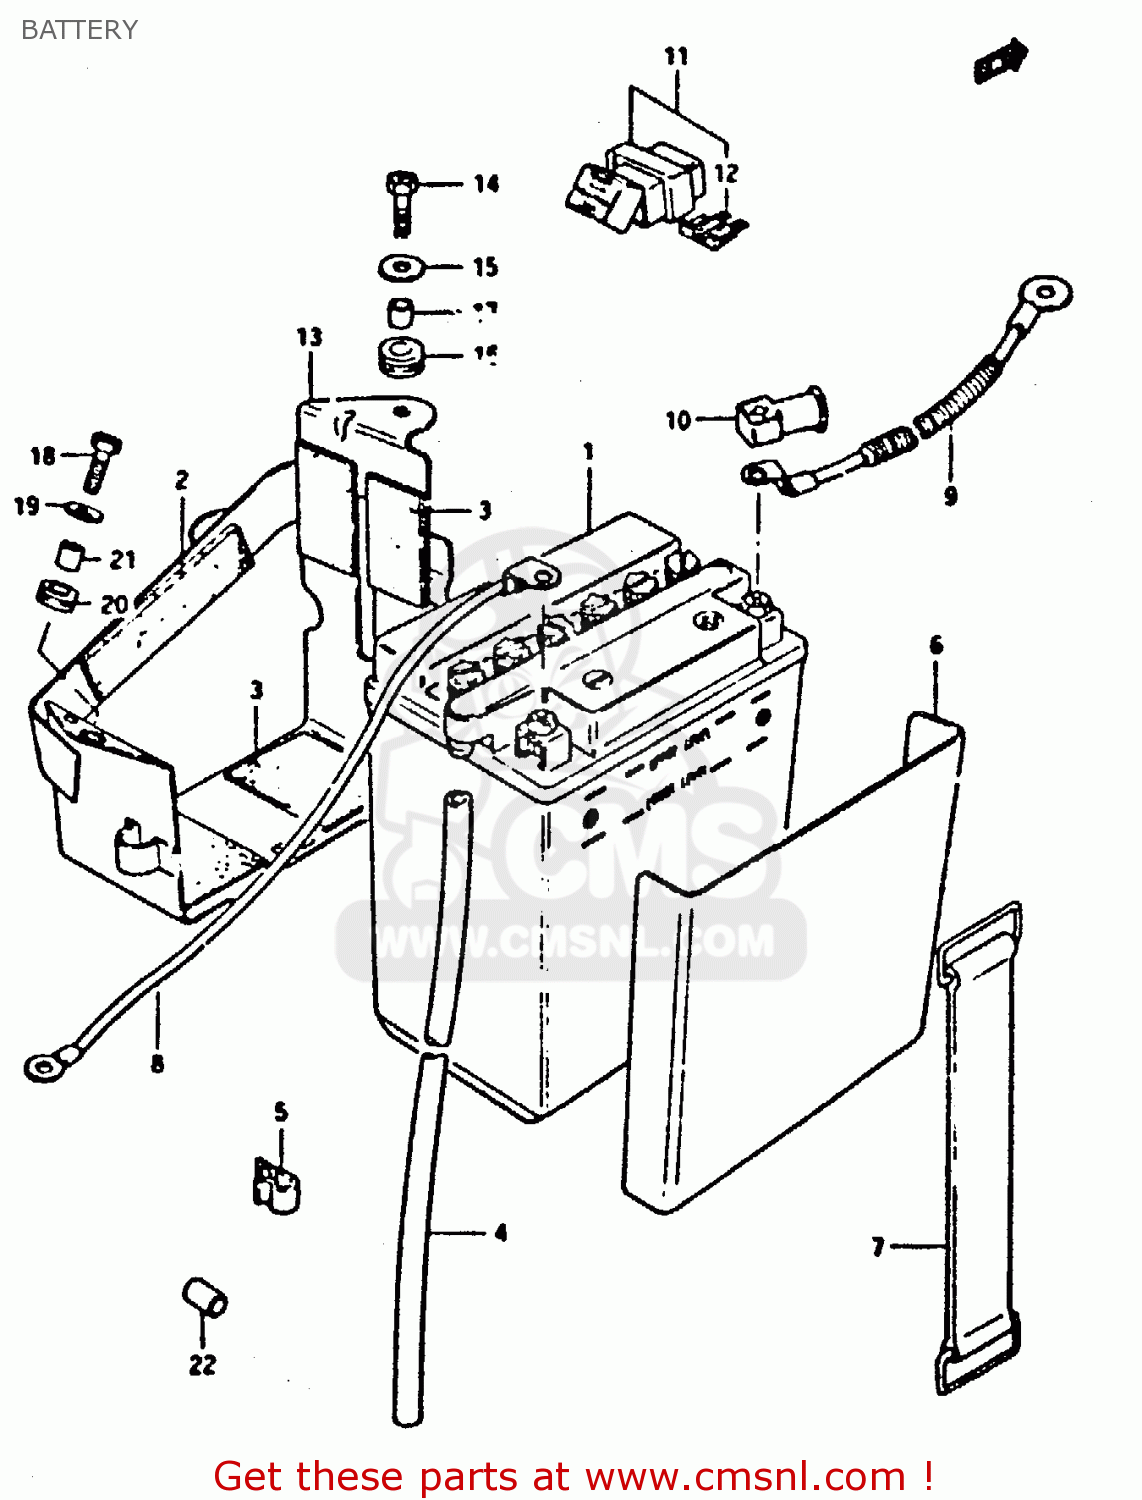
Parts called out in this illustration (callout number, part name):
1	BATTERY ASSY (12V)
2	PROTECTOR(20X90)X4
3	PROTECTOR,BATTERY
4	HOSE,BATTERY EXHAUST
5	CLAMP
6	COVER,BATTERY
7	BAND
8	WIRE,STARTER MOTOR LEAD
9	WIRE,BATTERY PLUS
10	CAP,BATTERY PLUS TERMINAL
11	BOX ASSEMBLY,FUSE
12	FUSE(20A)
13	HOLDER,BATTERY
14	BOLT L:16
15	WASHER (6.5X24X1.6)
16	CUSHION
17	SPACER(6.2X8.3X6.1)
18	BOLT(6X20)
19	WASHER
20	CUSHION
21	SPACER(6.1X9X7.5)
22	CUSHION
